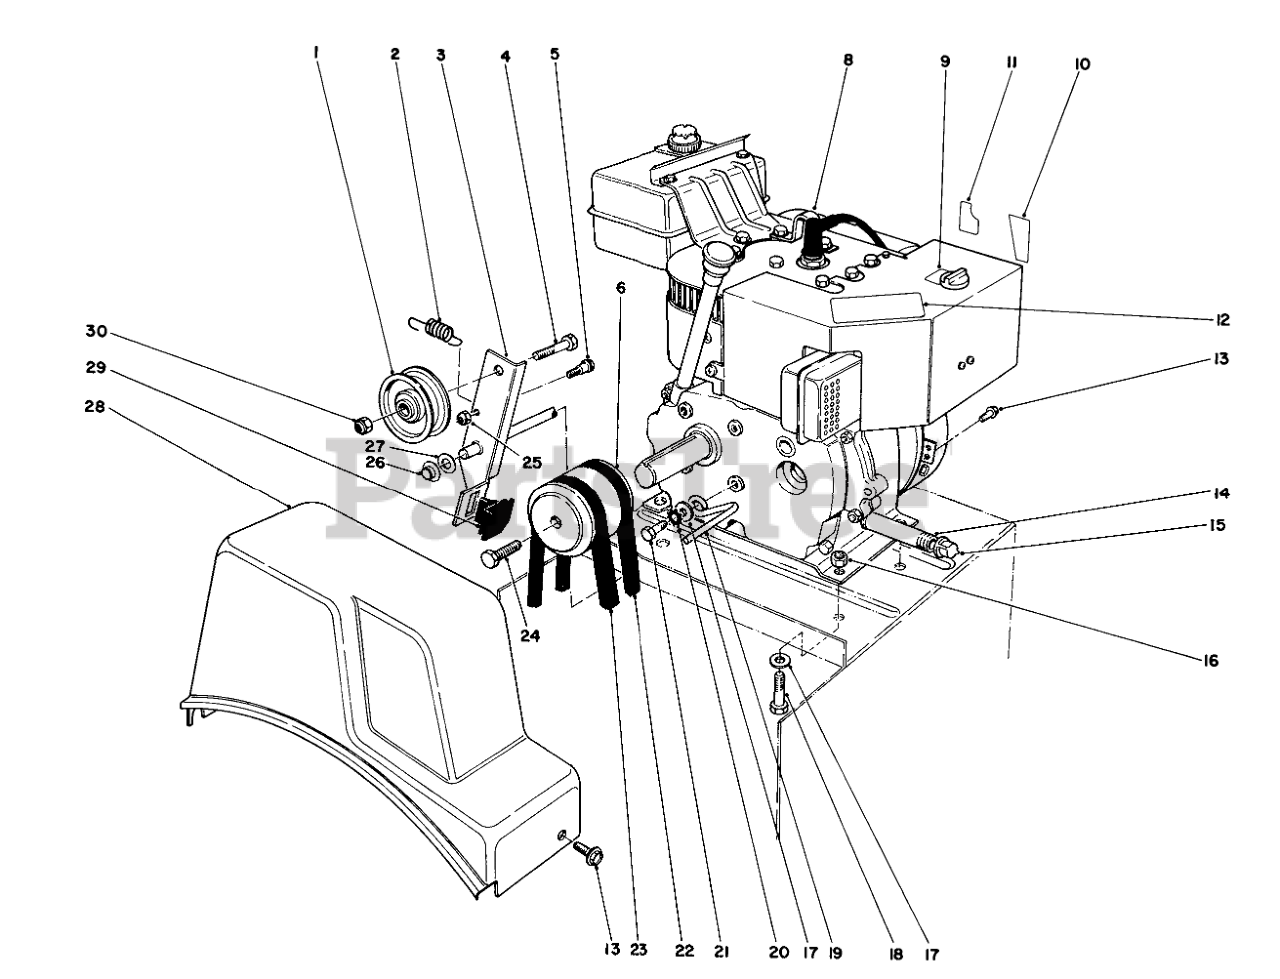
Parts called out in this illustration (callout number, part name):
1	PULLEY-IDLER
2	SPRING
3	Auger Clutch (Incl. ref. #29)
4	SCREW-HH
5	BOLT-SHOULDER
6	PULLEY-ENGINE
9	DECAL-CHOKE
10	DECAL-THROTTLE
11	DECAL-PRIMER
12	DECAL-WARNING, HOT SURFACE
13	SCREW-HWH
14	PIPE-NIPPLE
15	CAP-PIPE
16	NUT-LOCK, NI
17	WASHER-PLAIN
18	SCREW-HH
19	RETAINER-BELT
20	WASHER-LOCK
21	SCREW-HH
22	V BELT-3L, TRACTION
23	V-BELT
24	SCREW-SPECIAL
25	NUT-LOCK, NI
26	RETAINER-PUSH ON
27	WASHER-FLAT
28	COVER-BELT
29	PAD-BRAKE
30	NUT-LOCK, NI
